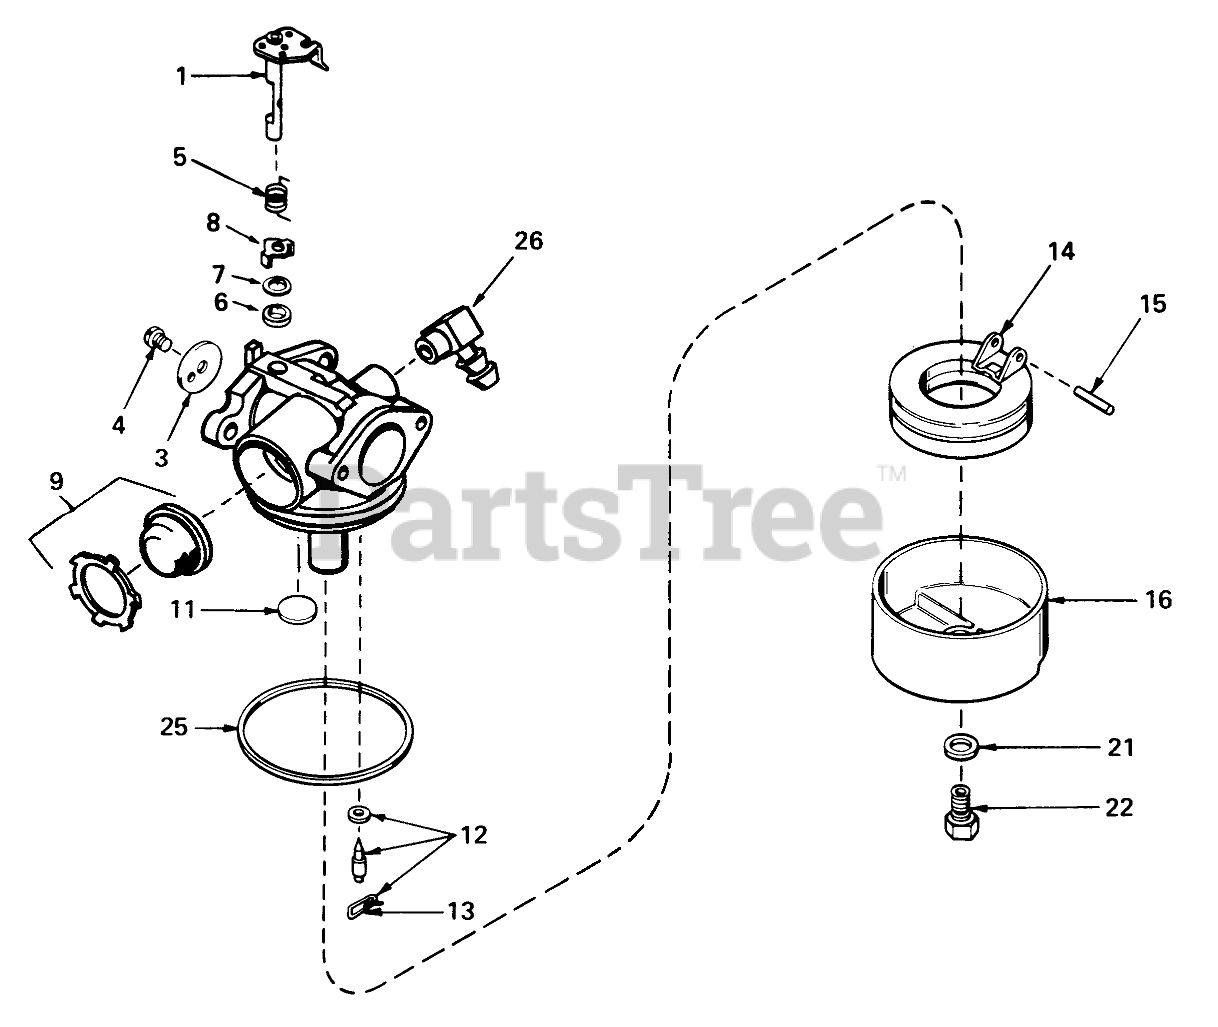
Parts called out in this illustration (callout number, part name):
1	Throttle Shaft and Lever ASM
3	Throttle-Shutter
4	Screw-Shutter
5	Spring, Return
6	Seal-Dust
7	Washer-Seal, Dust
8	Retainer, Seal
9	Primer Assy.
11	Plug-Welch, Atmospheric Vent
12	Inlet Needle, Seat & Clip Assembly (Incl. Ref.# 13)
13	Clip-Spring
14	Float
15	Shaft-Float
16	Bowl Float
21	Gasket-Bowl
22	Nut, Float Bowl
25	O Ring-Bowl, Float
26	Fitting-Fuel
